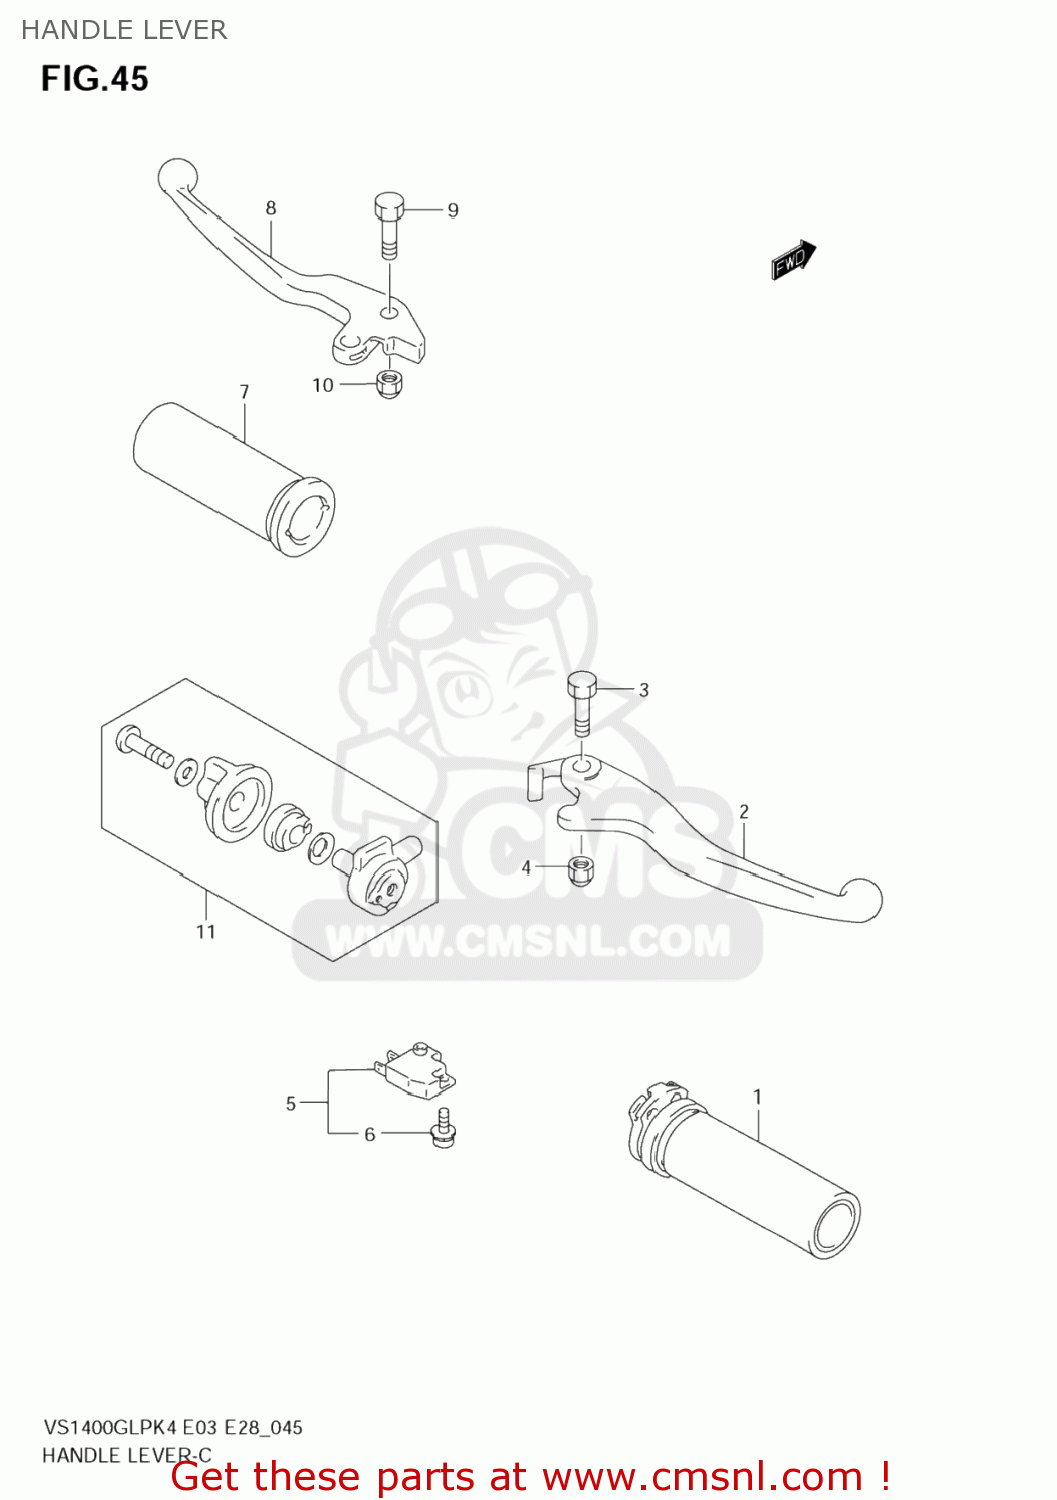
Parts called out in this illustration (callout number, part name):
1	GRIP,THROTTLE
2	LEVER,BRAKE
3	BOLT,LEVER SET
4	NUT 6MM
5	SWITCH ASSY,ST
6	SCREW
7	GRIP,L
8	LEVER,CLUTCH
9	BOLT,LEVER SET
10	NUT 6MM
11	LEVER ASSY,STARTER
